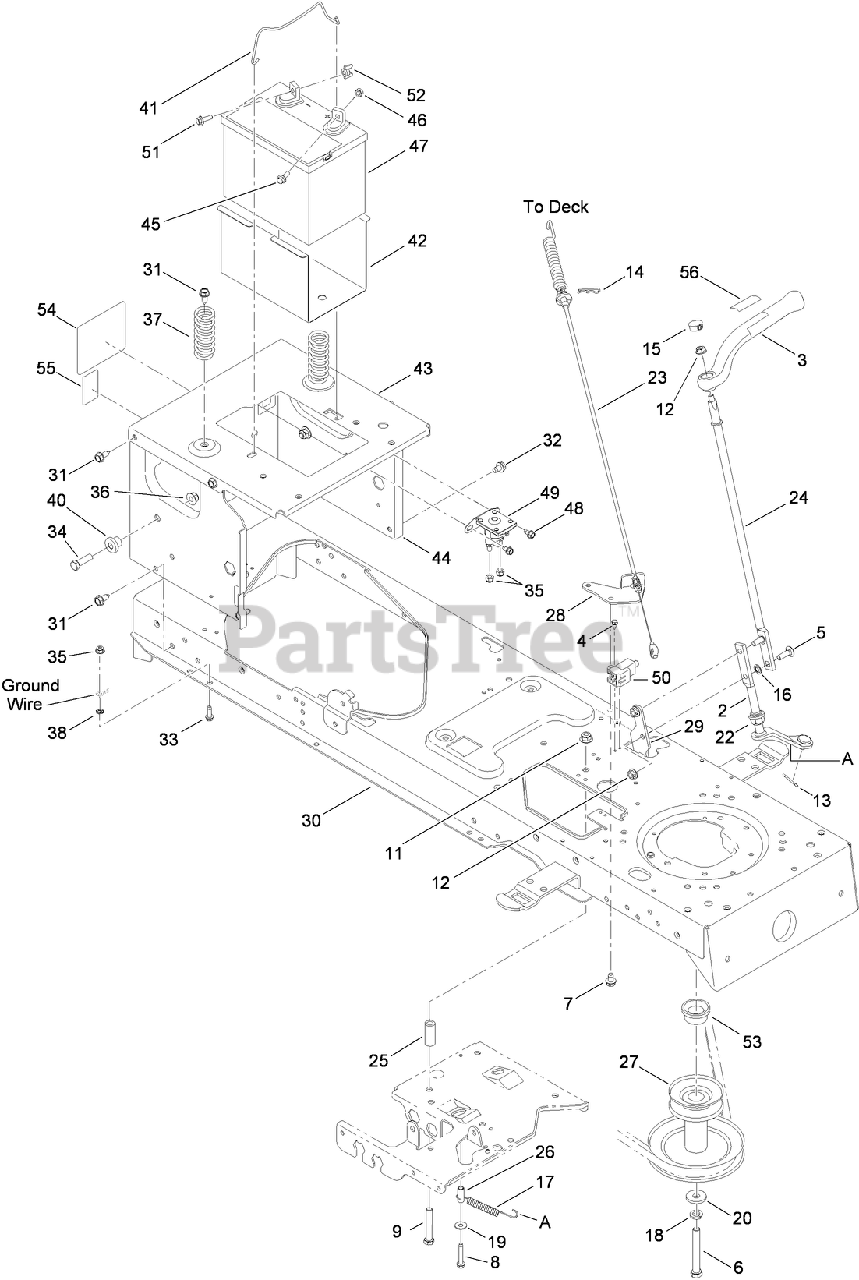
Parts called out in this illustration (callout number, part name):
2	LEVER-ENGAGE, PTO
3	KNOB PTO ASM
4	BOLT-SHOULDER
5	BOLT-CARR
6	SCREW-HH
7	SCREW-TAP
8	SCREW-HWH
9	SCREW-HH
11	NUT-LOCK, FLANGE
12	NUT-LOCK, FLANGE
13	PIN-COTTER
14	PIN-CLICK
15	PLUG-KNOB, PTO LEVER
16	NUT-PUSH
17	SPRING-EXTENSION
18	WASHER-LOCK
19	WASHER-FLAT
20	WASHER-FLAT
22	BEARING-FLANGE, HEX (SPLIT)
23	CABLE-ENGAGE, DECK
24	ROD-ENGAGE, DECK
25	SPACER
26	SPACER
27	PULLEY-ENGINE
28	BRACKET-MOUNT, CABLE
29	BRACKET-STOP
30	LOWER FRAME ASM
31	SCREW-TAP
32	SCREW-TAP
33	SCREW-TAP
34	SCREW-HH
35	NUT-LOCK, FLANGE
36	NUT-LOCK, FLANGE
37	SPRING-COMPRESSION
38	WASHER-LOCK, EXTERNAL
40	SPACER-SHOULDER
41	ROD-HOLDDOWN, BATTERY
42	TRAY-BATTERY
43	BRACKET-FRAME, SEAT
44	FRAME-UPPER
45	BOLT-CARRIAGE
46	NUT-SEMS
47	BATTERY-245, CCA,DRY (FLAT TOP)
48	SCREW-TAP
49	SOLENOID-12V, 2 POST 2 TAB
50	SWITCH-INTERLOCK, NO/NC
51	BOLT-SHOULDER
52	NUT-WING
53	SPACER
54	DECAL-TORO
55	DECAL-HYDRO RELEASE
56	DECAL-PTO
